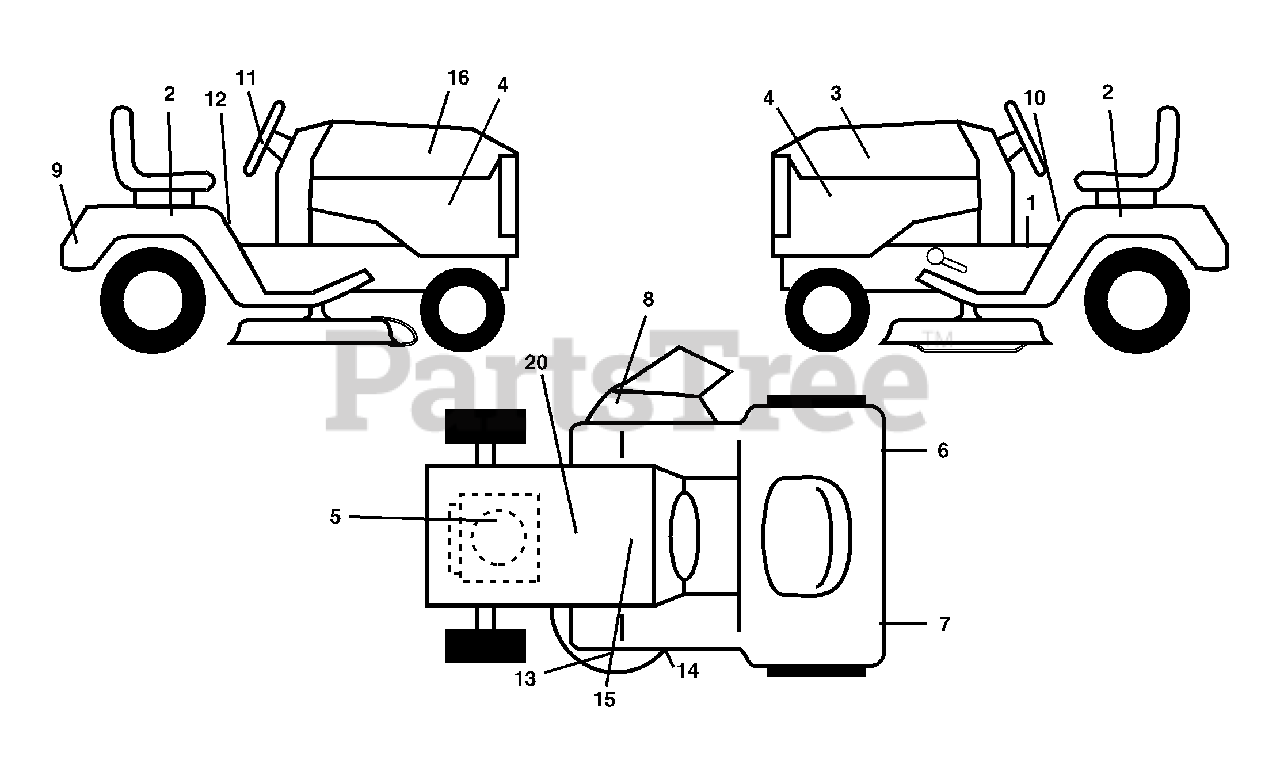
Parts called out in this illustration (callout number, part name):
1	Decal Dash
2	Decal Fender Auto
3	Decal Hood LH
4	Decal Side Panel
5	Decal HP Engine
6	Decal Reflector Rh
7	Decal Reflector Lh
9	Decal Fender Logo
10	Decal Fender Danger E/F
11	Decal Ins Strg Whl
12	Decal Fender Oper Cruise
13	Decal Deck Caution
14	Decal V-Belt Schematic
15	Decal Replace
16	Decal Hood Rh
20	Decal Bat Dan/Psn
